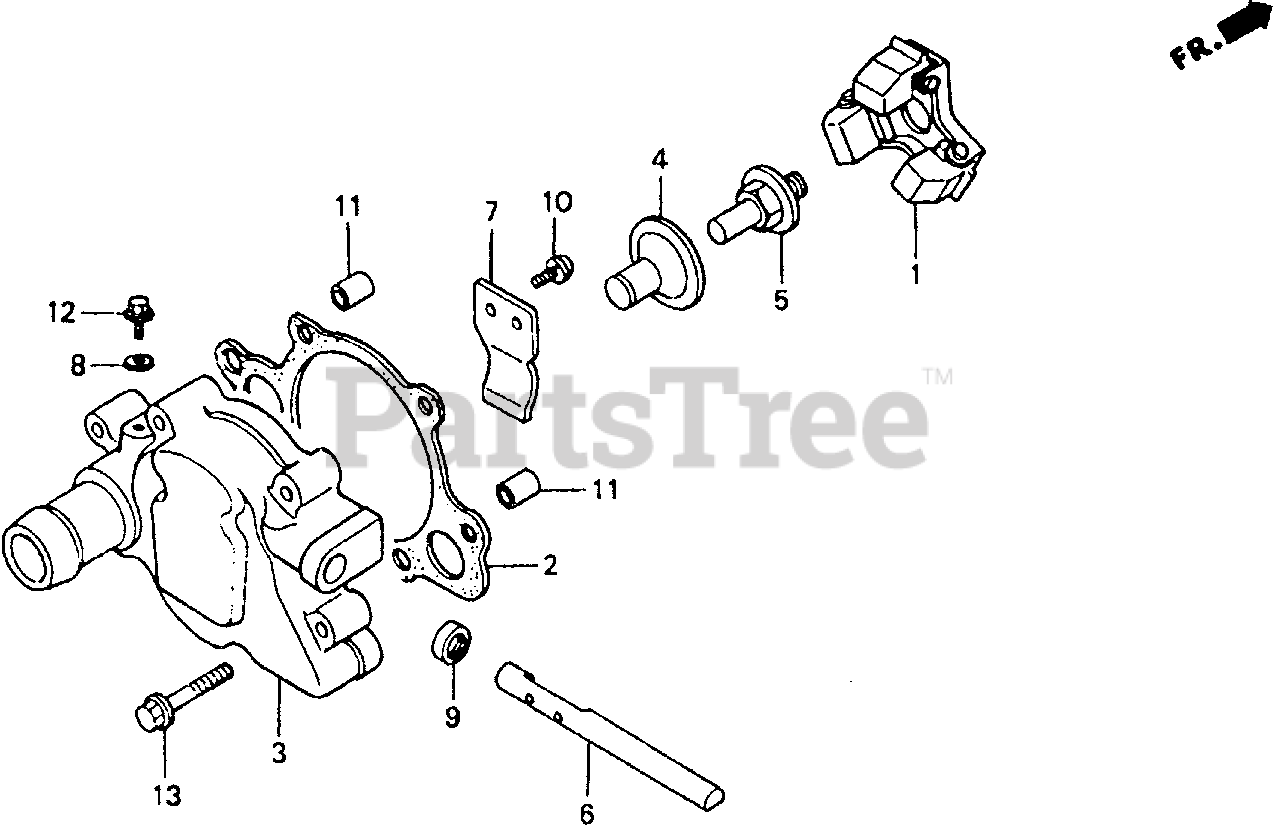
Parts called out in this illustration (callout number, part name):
1	WEIGHT, GOVERNOR
2	GASKET, GOVERNOR COVER
3	COVER, GOVERNOR
4	SLIDER, GOVERNOR
5	SHAFT, GOVERNOR
6	SHAFT, GOVERNOR
7	FORK, GOVERNOR
8	WASHER, SEALING (6MM)
9	OIL SEAL (10X16X4.5)
10	SCREW-WASHER (5X12)
11	PIN A, DOWEL (8X14)
12	BOLT, FLANGE (6X14)
13	BOLT, FLANGE (6X35)
